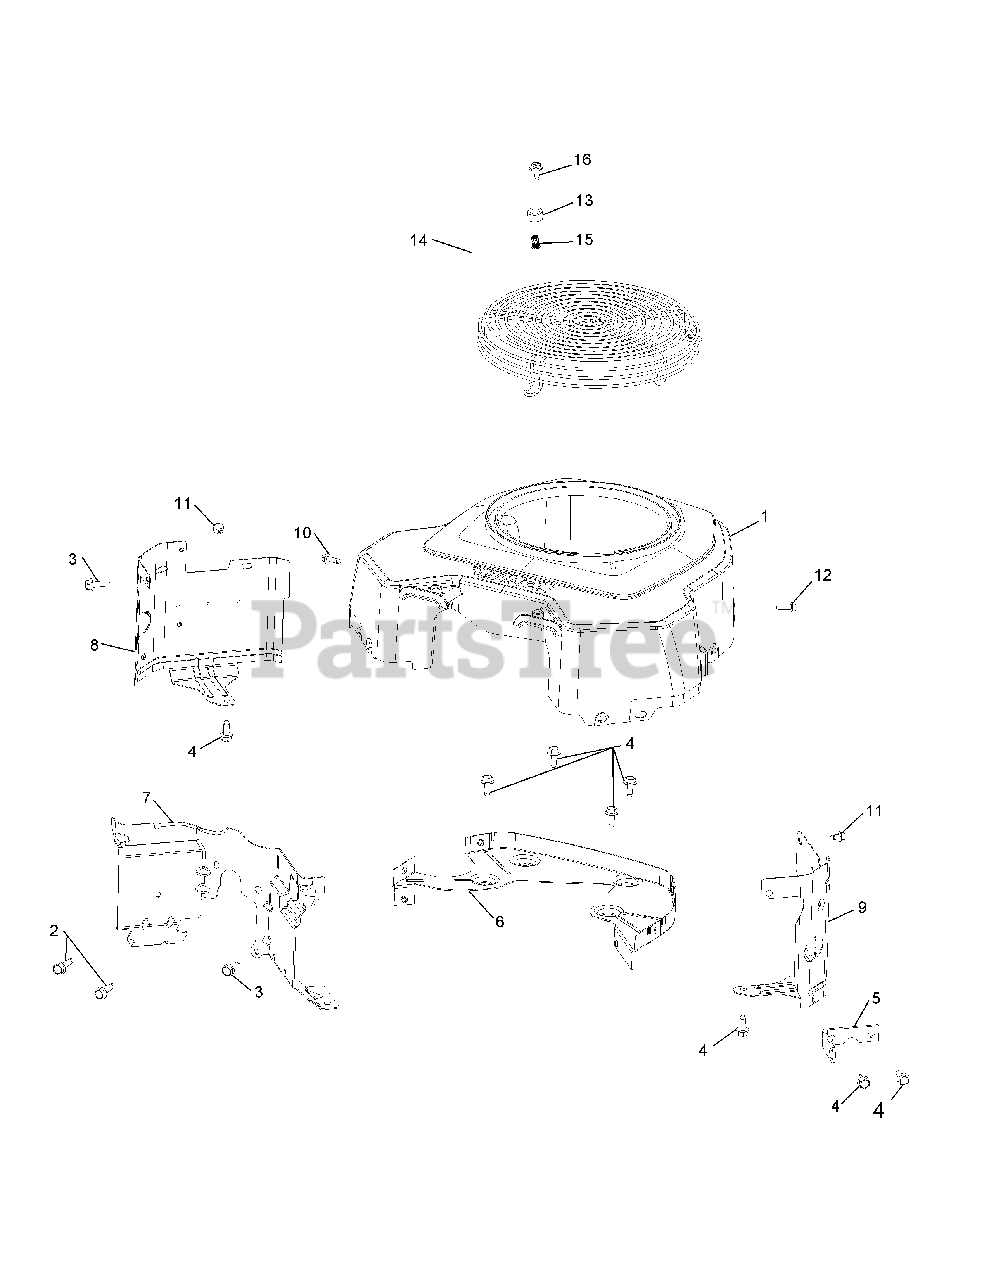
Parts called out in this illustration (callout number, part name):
1	Blower Housing
2	Thread Forming Screw
3	Thread Forming Screw
4	Thread Forming Screw
6	Backing Plate Kit
8	Cylinder Barrel Kit, #1 Side
9	Cylinder Baffle Kit, #2 Side
10	Thread Forming Screw
11	Thread Forming Screw
12	Thread Forming Screw
14	Guard Kit (Inc. 13, 15-16)
15	Threaded Insert
